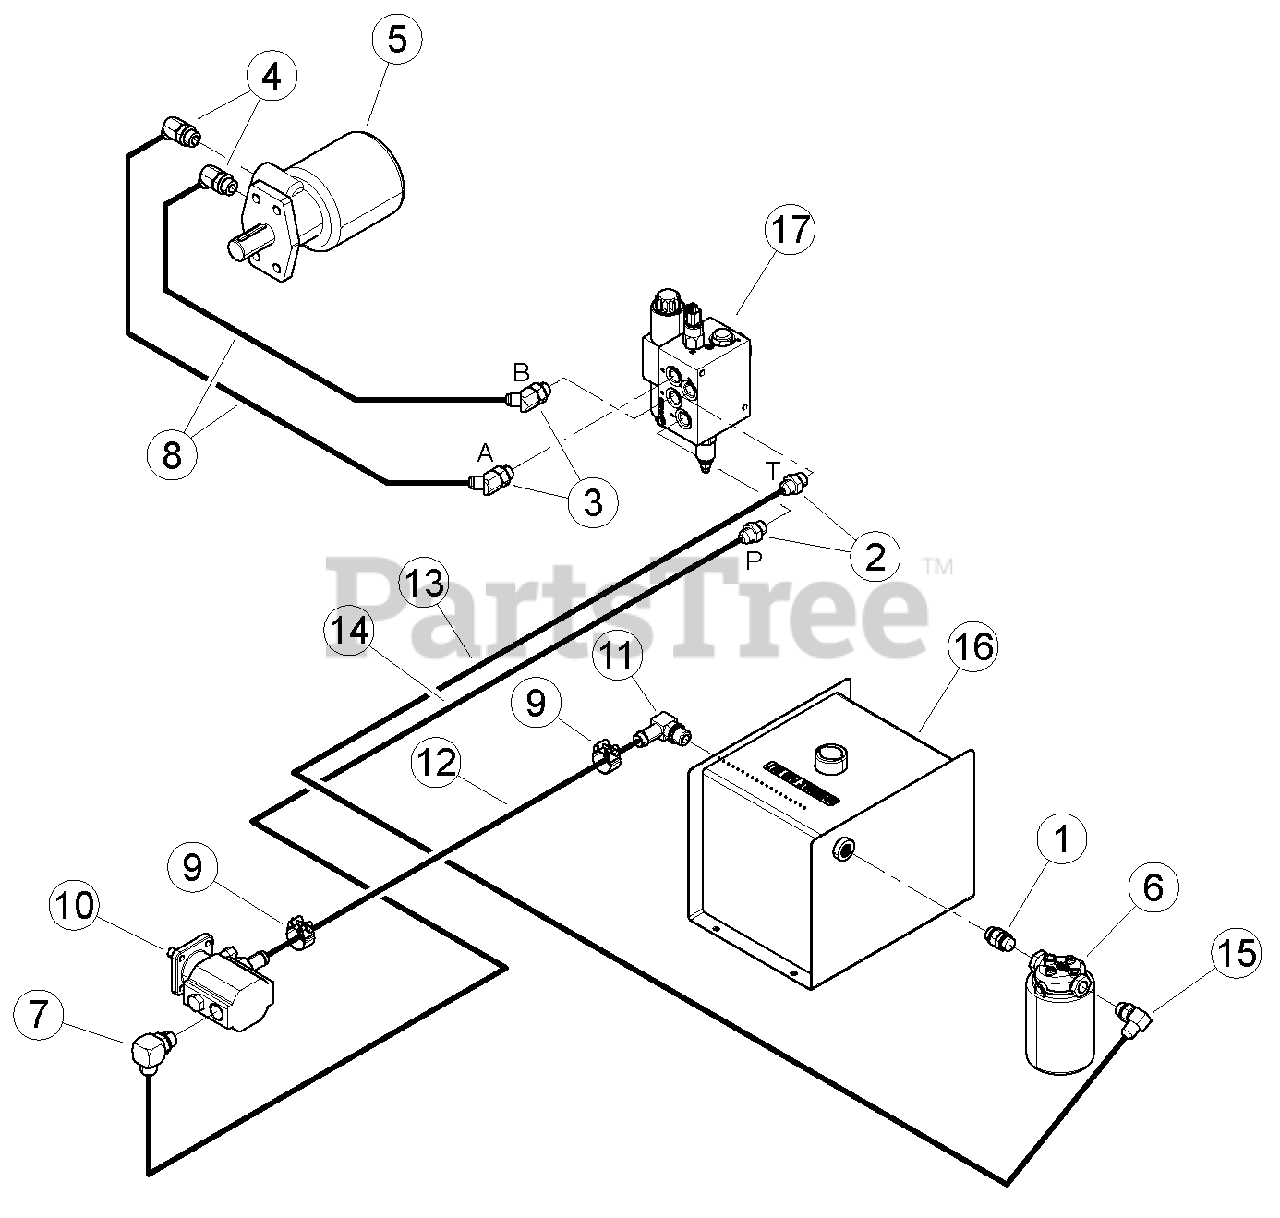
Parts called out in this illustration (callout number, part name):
1	ADAPTER, -8 MORING / -8 MORING ADJ
2	ADAPTER, -8 MORING / -8 MJIC
3	ADAPTER, -8 MORB / -8 MJIC 45 DEG.
4	ADAPTER, -10 MORING / -8 MJIC 45 DEG.
5	MOTOR, 45 CU IN HYDRAULIC
6	ASSEMBLY, HYDRAUILC FILTER
7	ADAPTER, -10 MORING / -10 MJIC 90 DEG.
8	HOSE, .375 X 36" -8 FMJIC / -8 FMJIC
9	CLAMP, 1-5/32 TO 7/32 OD RANGE T-BOLT
10	PUMP, 2 STAGE CW HI/LO 0.605 DISP.
11	ADAPTER, -10 MORING / .75 90 DEG. HOSE
12	HOSE, .75 ID X 38" 100R4 HYD
13	HOSE, .50 X 84" -8 FMJIC / -8 FMJIC
14	HOSE, .50 X 66" -8 FMJIC / -10 FMJIC 90 DEG.
15	ADAPTER, -8 MORING / -8 MJIC 90 DEG.
16	ASSEMBLY, HYDRAULIC TANK
17	ASSEMBLY, HYDRAULIC FEED FLOW VALVE
